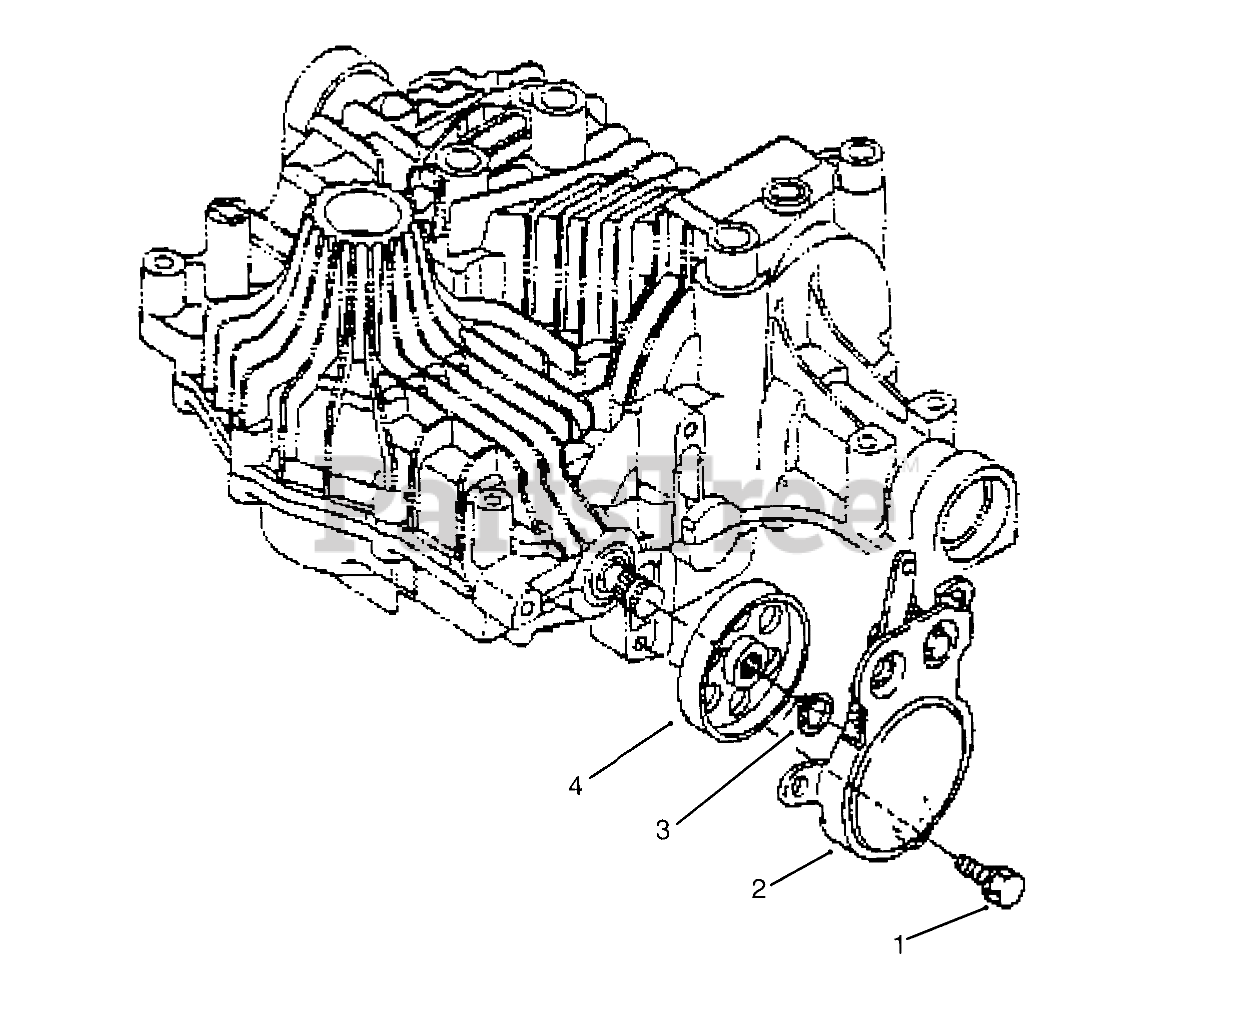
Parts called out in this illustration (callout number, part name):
1	Bolt W/Washer (Only On: 72043,72063,72103)
2	Band-Brake Interlock (Only On: 72043,72063,72103)
3	Ring-Snap (Only On: 72043,72063,72103)
4	Drum-Brake (Only On: 72043,72063,72103)
